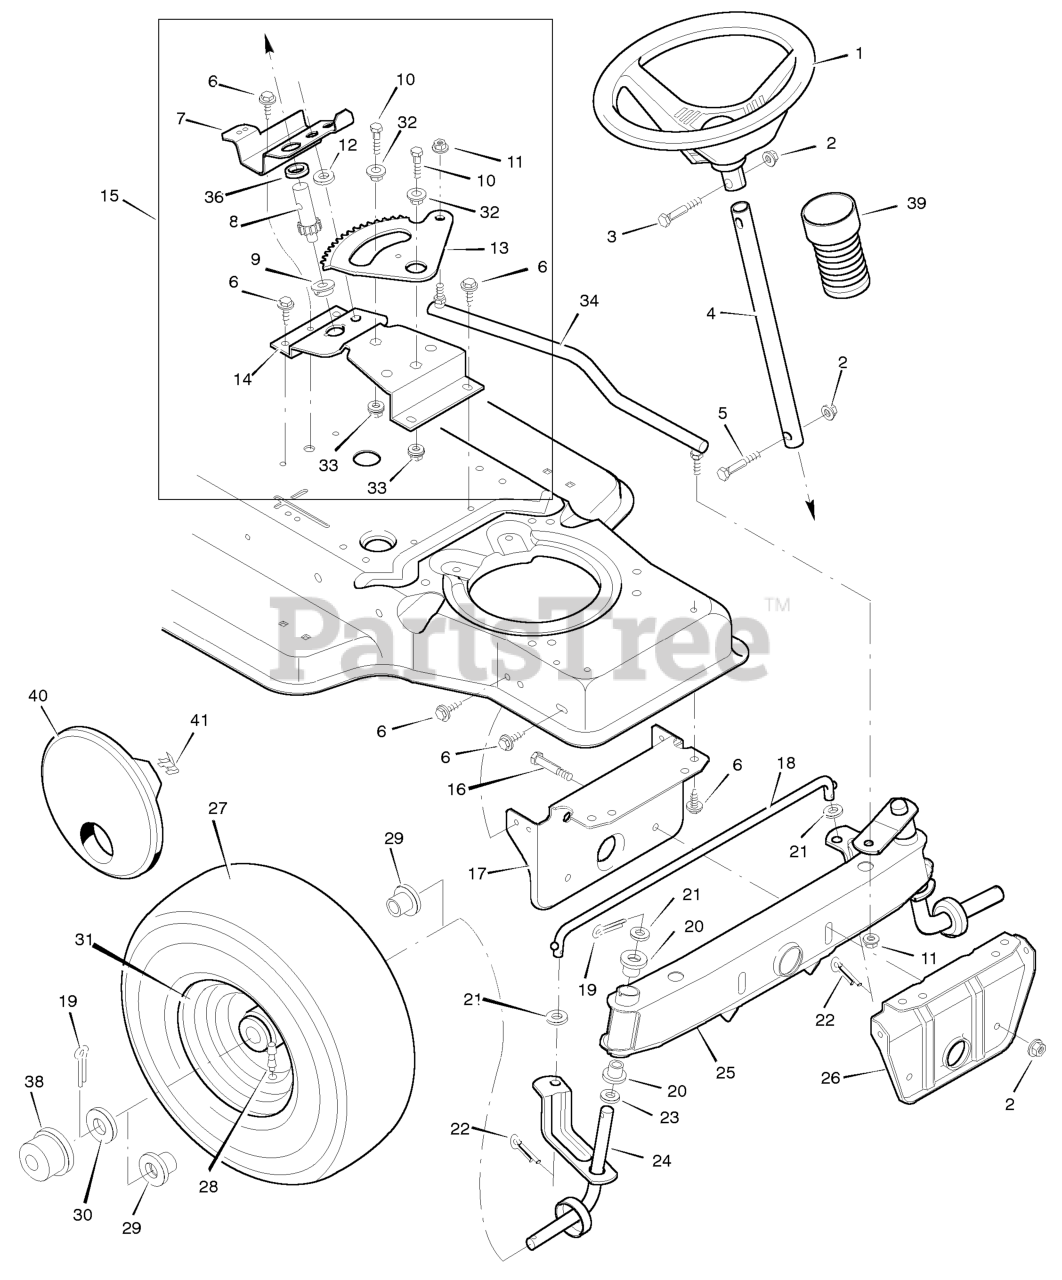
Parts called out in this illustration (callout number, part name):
1	Wheel, Steering
2	Nut, Hex
3	Bolt, Hex
4	Post, Steering
5	Bolt, Hex
7	Bracket, Sector
8	Gear, Pinion
9	Bearing
10	CAPSCREW, Hex Head, 5/16-18 x 1
11	Locknut, Flange
13	Gear, Sector
14	Bracket, Sector
15	Kit, Steering Gear
16	Bolt, Hex
17	Support, Rear Axle
18	Rod, Tie
19	Pin, Cotter
20	Bearing
22	Pin, Cotter
24	Spindle Assembly, Right
25	Spindle Assembly, Axle & Left
26	Support, Front Axle
27	Tire *
28	Stem, Valve
29	Bearing, Wheel
31	Wheel & Tire Assembly
32	Bearing
33	Locknut, Flange
34	Link, Drag
36	Spacer, Pinion Gear
38	Hub Cap
39	Bellows
40	Disc, Wheel
41	Clip, Retainer
